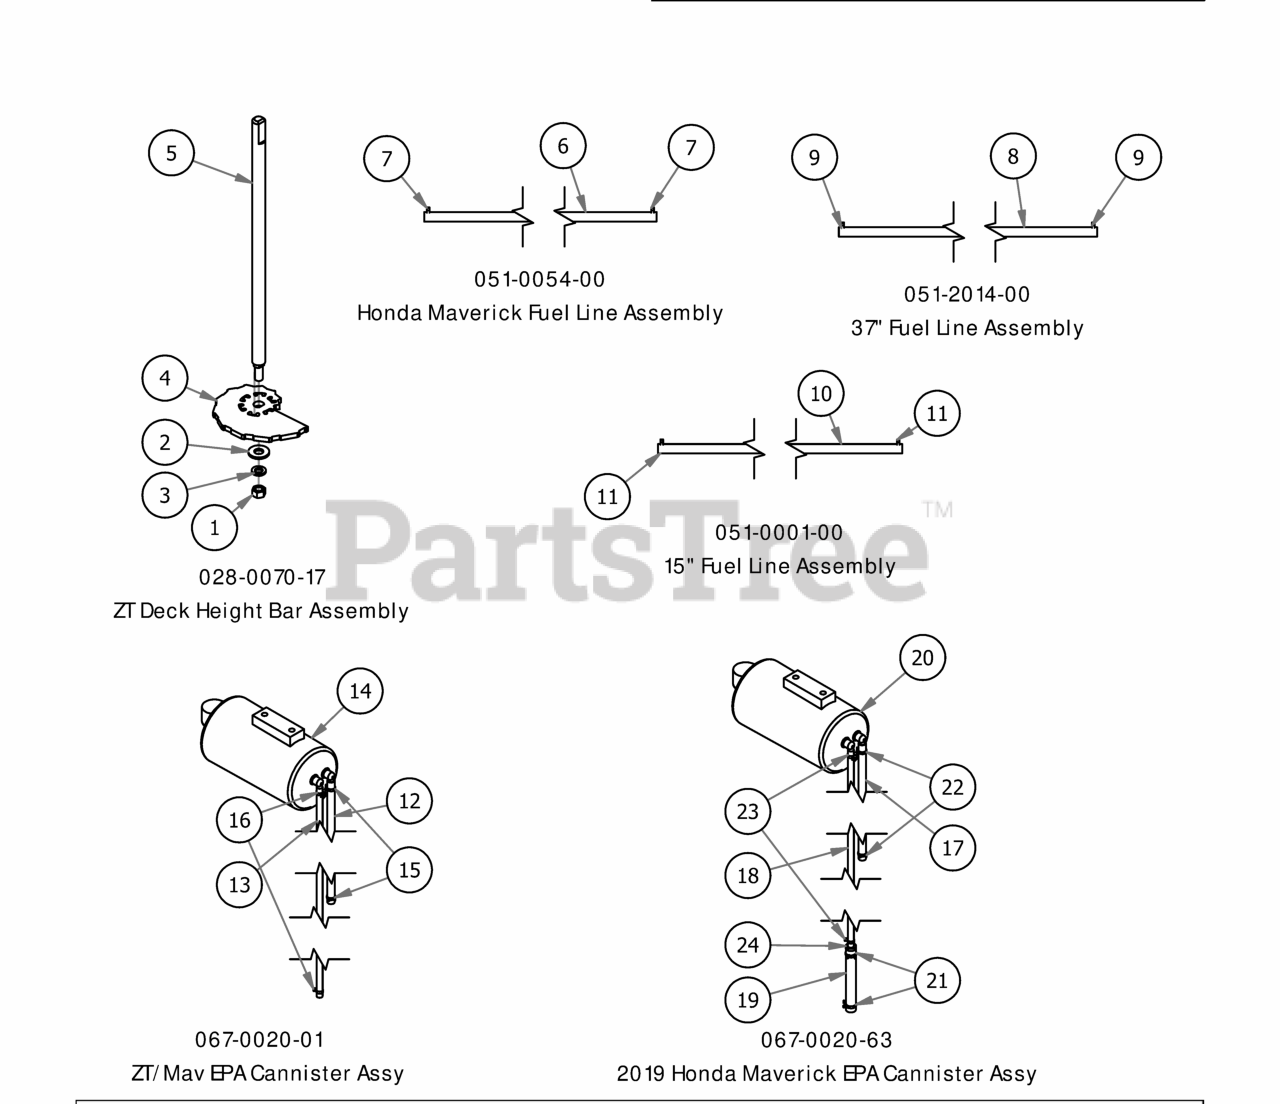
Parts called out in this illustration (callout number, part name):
1	3/8" Fine Threaded Jam Nut
2	3/8" Flat Washer
3	3/8" Lock Washer
4	2017 MZ/ZT Cam Plate
5	2017 Deck Height Dial Rod ZT
6	1/4 Fuel Line, 54"
7	1/4 Fuel Hose Clamp
8	37" 1/4 Fuel Line
9	1/4 Fuel Hose Clamp
10	1/4 Fuel Line
11	1/4 Fuel Hose Clamp
12	1/4" Vinyl Tubing, 46" Long
13	3/16" Vinyl Tubing, 55" Long
14	Carbon Canister
15	3/16 Vinyl Clamp
16	3/16" Vinyl Hose Clamp
17	1/4" Vinyl Tubing, 46" Long
18	3/16" Vinyl Tubing, 55" Long
19	3/8" PVC Tubing, 3.6" Long
20	Carbon Canister
21	5/16 Fuel Line Clamp
22	3/16 Vinyl Clamp
23	3/16" Vinyl Hose Clamp
24	3/8-1/4 Nylon Reducer
